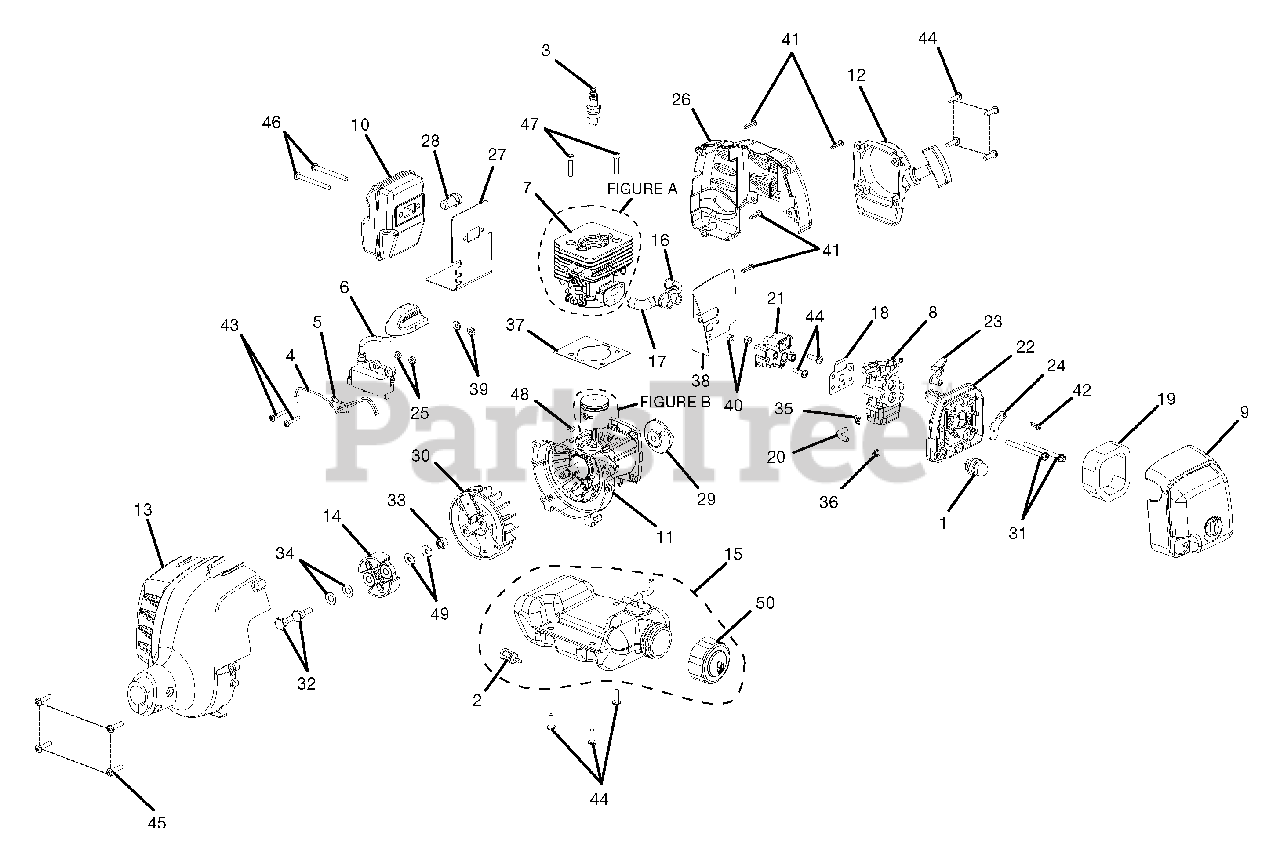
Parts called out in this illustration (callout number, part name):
1	Primer Assembly
2	Fuel Filter
3	Spark Plug
4	Lead Assembly, Black
5	Lead Assembly, Red
6	Coil, Boot, Assembly
7	Cylinder Assembly
8	Carburetor Assembly
9	Cover Assembly
10	Muffler Assembly
11	Crankcase Assembly
12	Starter Recoil Assembly
13	Front Housing Assembly
14	Clutch Assembly
15	Fuel Tank Assembly
16	Pipe, Air, Starter Side
17	Pipe, Air, Flywheel Side
18	Carburetor Gasket
20	Tubing, Plastic Rubber
21	Insulator, Heat Dam
22	Carburetor Plate
23	Choke Lever
24	Choke Plate
25	Ignition Coil Spacer
26	Engine Housing, Rear
27	Muffler Gasket
28	Spark Arrester
30	Rotor, Permanent Magnet
31	Screw (M5 x 0.8 x 60 mm, Slotted Recessed Pan Head, Machine)
32	Clutch Screw
33	Rotor Nut
34	Curved Washer
35	Hose Clip
36	Hose Clip
38	Insulator Gasket
39	Type A, Plain Washer (3/16 x 7/16 x 3/64, Steel, Zink )
40	Nut, (M5 x .8 mm) Black Oxide
41	Screw (M4 x 1.75 x 16 mm, Type TT, Slotted Recessed Pan)
42	Screw (M4 x 1.75 x 12mm, Type TT, Slotted Recessed Pan Head)
43	Screw (M4 x 0.7 x 22 mm, Torx Recessed Pan Head Machined )
44	Screw (M5 x 0.8 x 16 mm, Torx Recessed Pan Head, Machine)
45	Screw (M5 x 0.8 x 20 mm, Torx Recessed Pan Head, Machine)
46	Screw (M5 x 0.8 x 50 mm, Torx Recessed Pan Head, Machine)
47	Screw (M5 x 0.8 x 22 mm, Socket Head Cap, Black Oxide)
48	Woodruff Key ( 10 mm x 3.7 mm x 3 mm)
50	Fuel Cap
